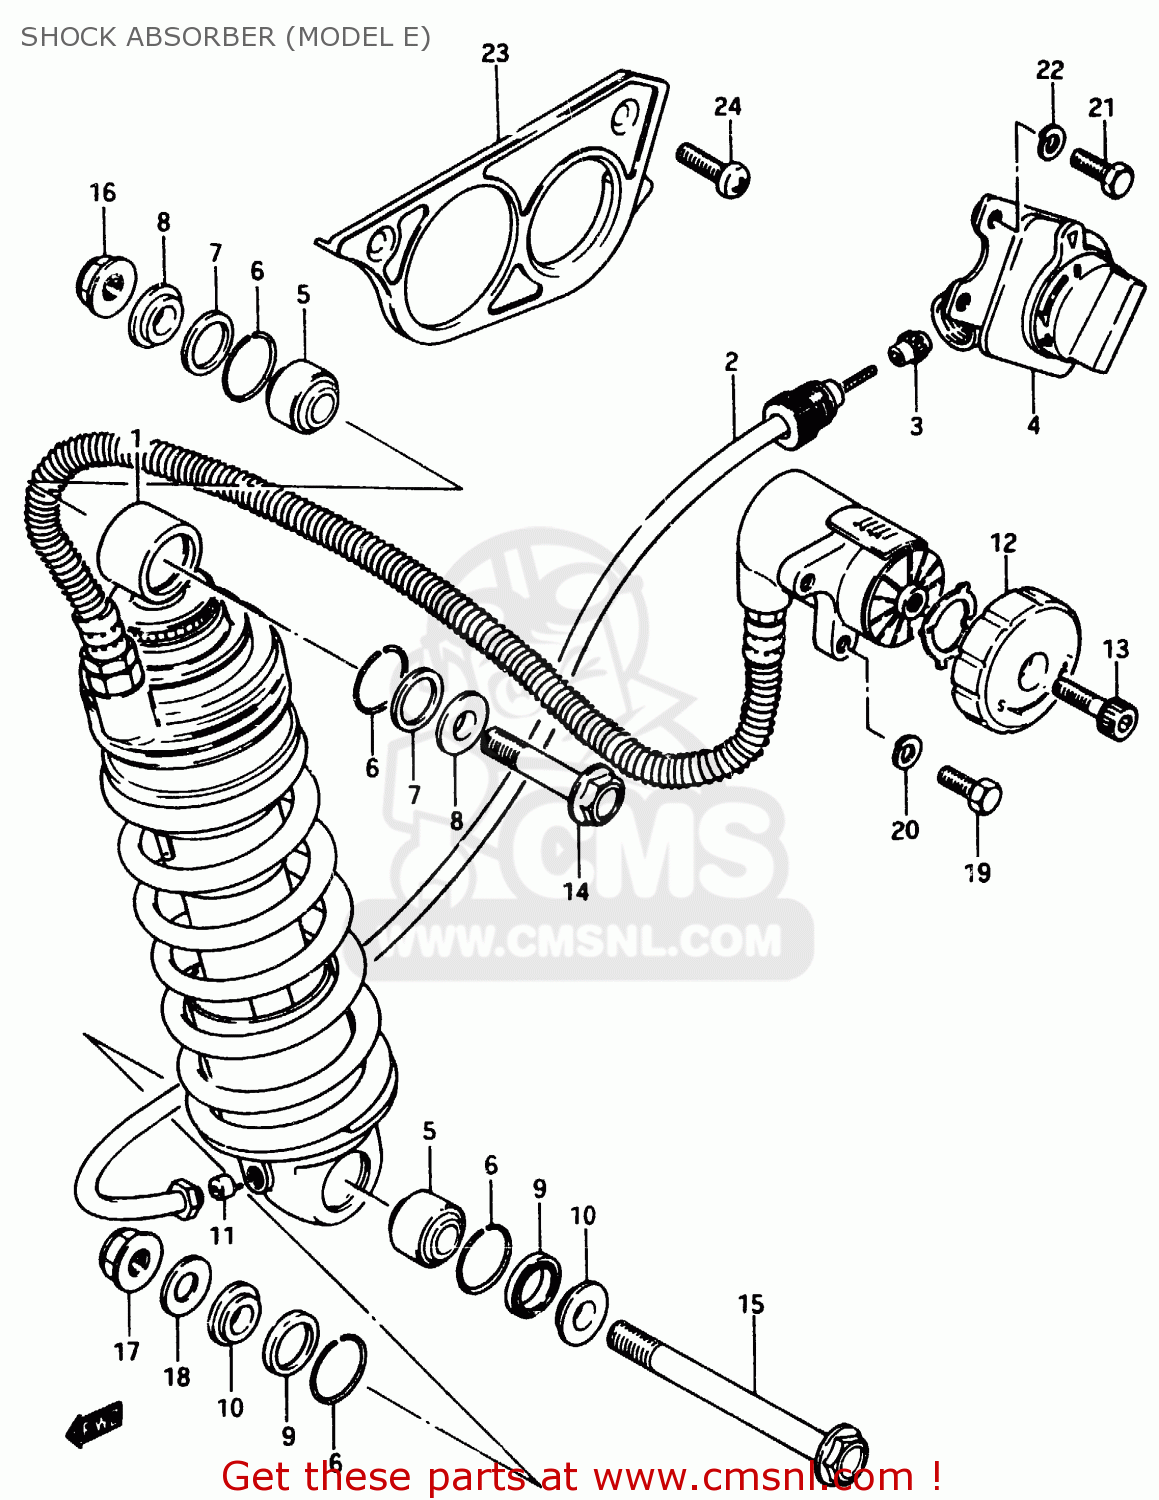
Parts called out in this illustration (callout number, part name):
1	MONO GSX750ESG
2	CABLE,CONTROL
3	GEAR
4	ADJUSTER
5	BEARING,REAR SHOCK ABSORBER
6	RING
7	DUST SEAL
8	SPACER
9	SEAL,DUST
10	COLLAR
11	CAM,DAMPER ADJUSTER
12	PLATE,LEVELING
13	BOLT
14	BOLT(10X50)
15	BOLT(10X115)
16	NUT
17	NUT
18	WASHER
19	BOLT 6X16
20	LOCK WASHER
21	BOLT 6X16
22	LOCK WASHER
23	COVER,REAR SHOCK ABSORBER ADJUSTER
24	SCREW
